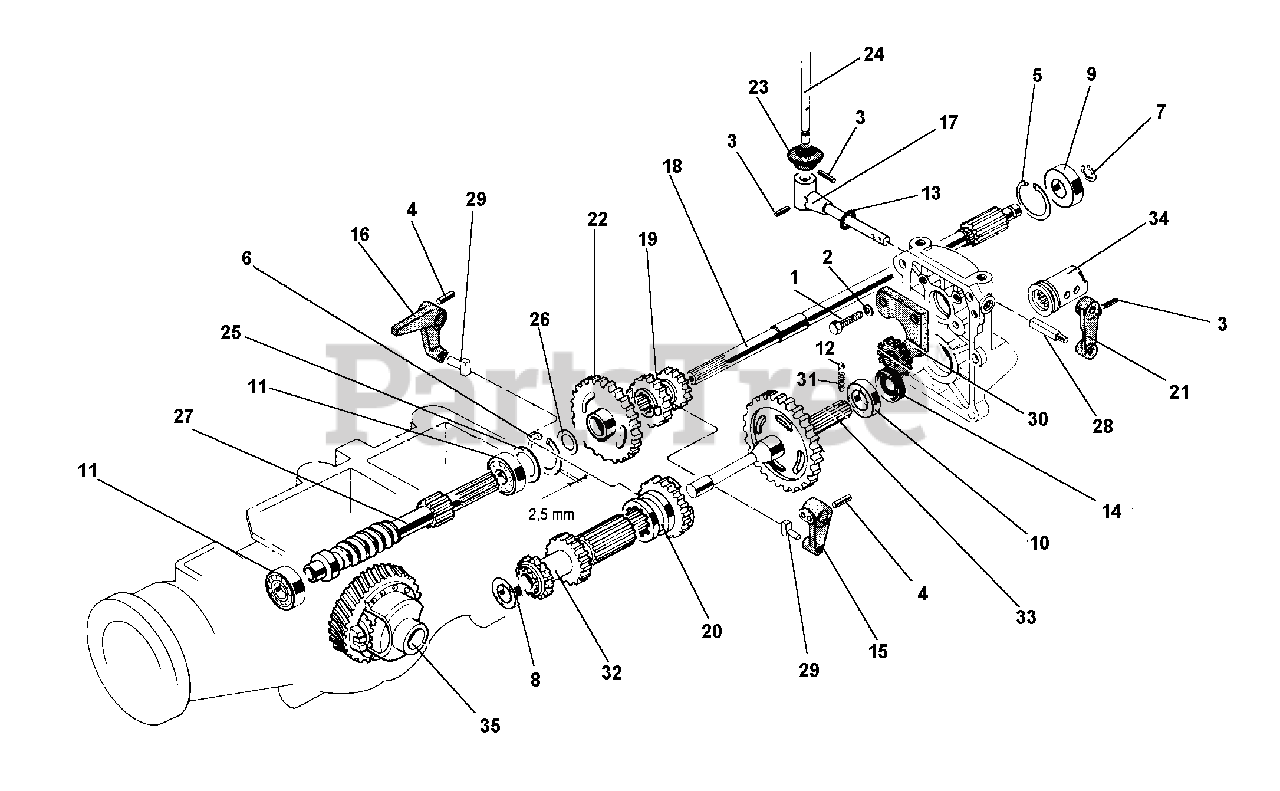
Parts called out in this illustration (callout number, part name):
1	SCREW M10 X 30
2	SUPER WASHER 10
3	LOCKING PIN 4 X 20 SPIRAL
4	LOCKING PIN 4 X 24 SPIRAL
5	CIRCLIP, INTERNAL
6	CIRCLIP INTERNAL DIAM. 52
9	BEARING 15 X 42 X 13
10	BEARING 25 X 52 X 15
14	OIL SEAL 25 X 40 X 7
15	LEVER, SPEED CHG SLDG GR
16	LEVER, REVERSER
17	PTO CONTROL PIN
18	CLUTCH SHAFT FOR REVERSER
19	DOUBLE SLIDER
20	SLIDER, REVERSER
22	WHEELS FIRST SPEED
23	PTO STOP RING
24	PTO CONTROL LEVER
26	WASHER 25 X 32 X 2 C-72
30	GEAR, REVERSER
31	SPRING D6.2 X 15
34	PTO COUPLING
35	DIFFERENTIAL
